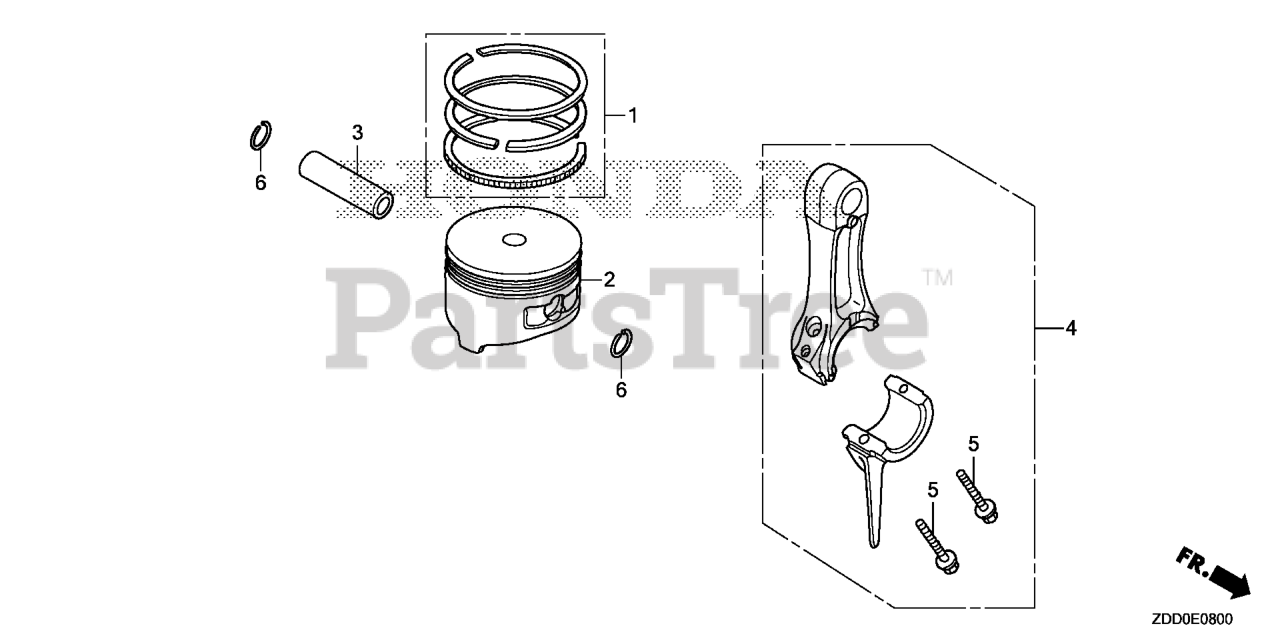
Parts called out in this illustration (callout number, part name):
1	RING SET, PISTON
3	PIN, PISTON
4	ROD ASSY., CONNECTING
5	BOLT, CONNECTING ROD
6	CLIP, PISTON PIN (13MM)
